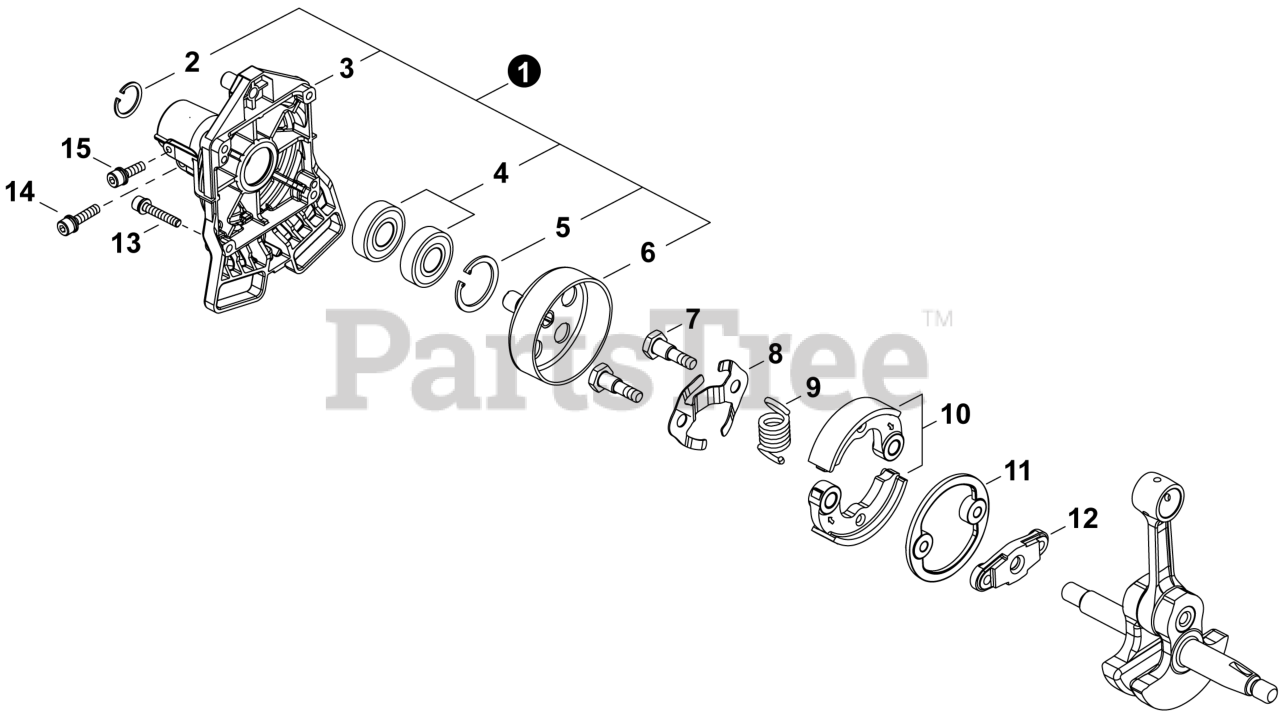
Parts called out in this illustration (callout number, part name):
1	CASE ASSY, CLUTCH
2	RING, SNAP 12
3	CASE, CLUTCH
4	BEARING, BALL
5	RING, SNAP 28
6	DRUM, CLUTCH
7	BOLT, CLUTCH
8	SPRING, FLAT
9	SPRING, CLUTCH
10	CLUTCH SHOE SET
12	HUB, CLUTCH
13	BOLT, TORX 5×25
14	BOLT, TORX 5×20
15	BOLT, TORX 5×10
